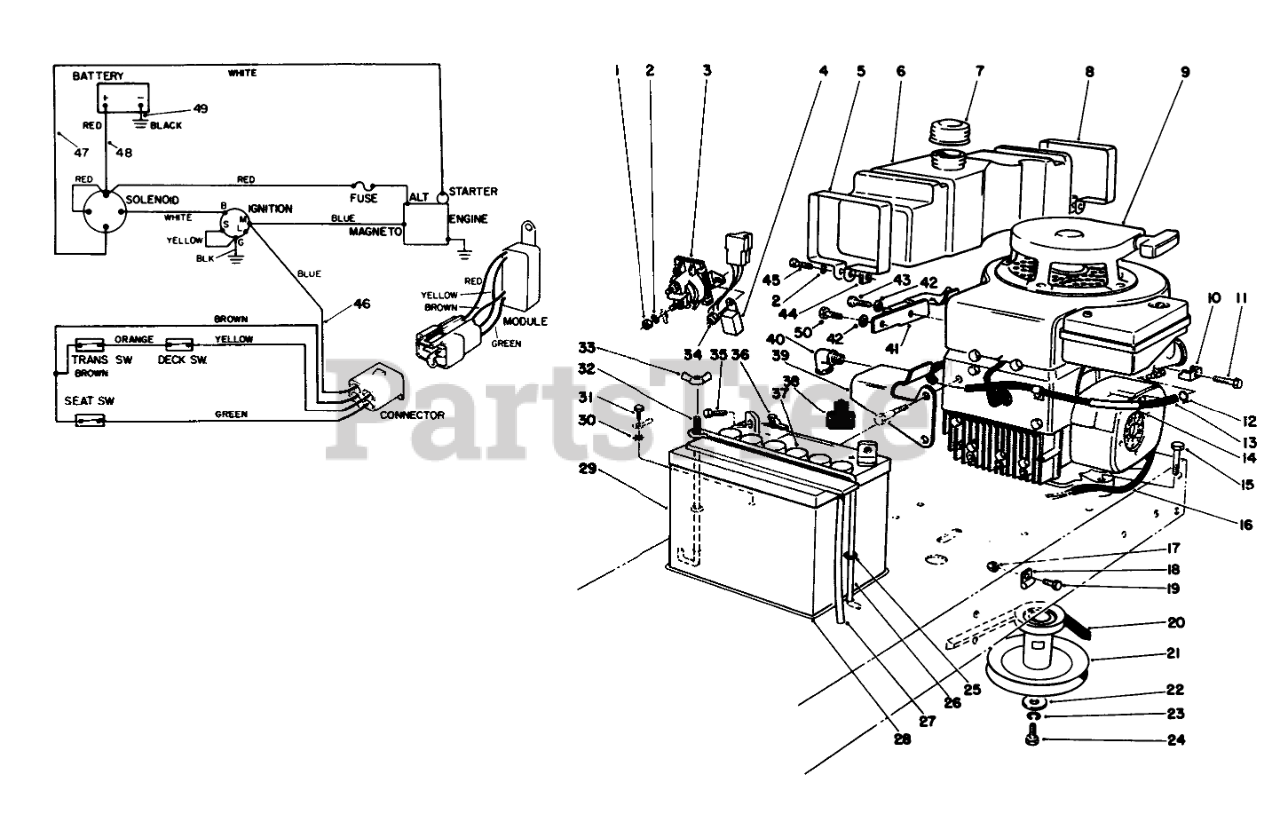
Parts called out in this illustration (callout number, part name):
1	NUT-JAM
2	WASHER-LOCK
3	SOLENOID
4	INTERLOCK MODULE
5	Retainer-Front
6	TANK-5 QT GAS
7	GAS CAP ASM
8	Retainer-Rear
9	Engine-8 H.P. (Model 56150)
10	CLAMP-CASING
11	SCREW W ENGINE
12	FUEL HOSE CLAMP
13	HOSE-FUEL
14	SUPPORT-FUEL LINE
15	SCREW-HH
16	HEAT SHRINK TUBING
17	NUT-LOCK, NI
18	CLAMP
19	SCREW-HH
20	V-BELT, TRACTION
21	PULLEY
22	WASHER-FLAT
23	WASHER-LOCK
24	SCREW-HH
25	O-RING
26	HOLDDOWN-BATTERY
27	TUBE-BATT DRAIN/80-2600
28	PAD-SKID, ANTI
29	Battery
30	WASHER-LOCK, INTERNAL
31	SCREW-HHF
32	POST-BATTERY
33	NUT-WING
34	NUT-LOCK, CONE
35	SCREW-HH
36	NUT-WING
37	CAP-BATTERY
38	BOOT-TERMINAL
39	FRT TANK MTG BRKT B
40	ELBOW-STREET, 90 DEG
41	REAR TANK MTG BRKT B
42	WASHER-PLAIN
43	SCREW-HH
44	NUT-SQUARE
45	SCREW-HSH
46	WIRE HARNESS
47	STARTER WIRE HARNESS
48	WIRE ASM
49	WIRE ASM(BATT/GRD.
50	SCREW-HH
